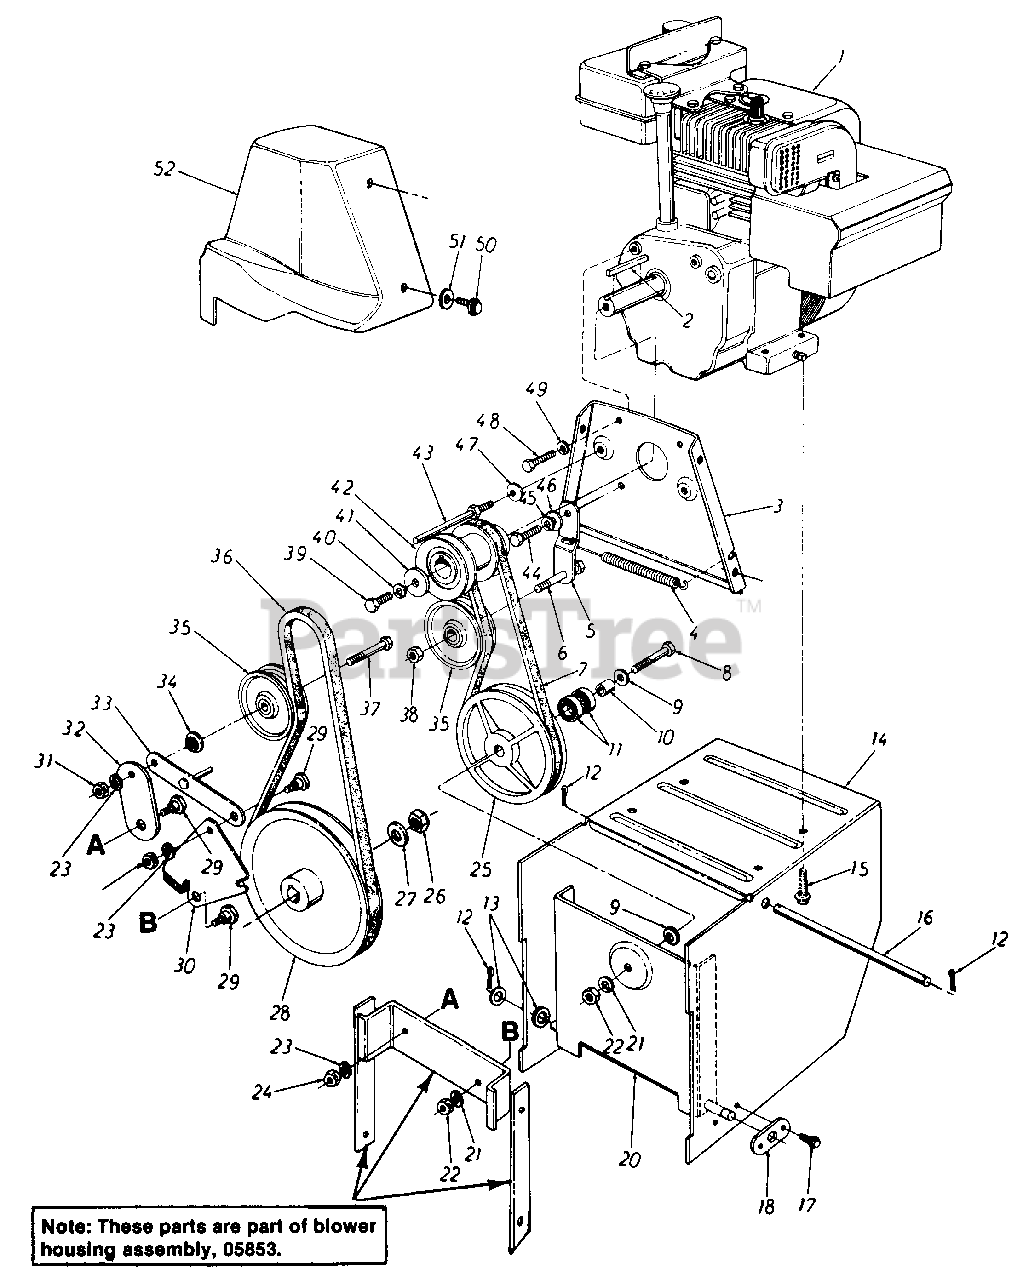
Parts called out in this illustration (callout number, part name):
1	Engine - 5 H.P.
2	Sq. Key 3/16" x 3/16" x 1.50" Lg.
3	Engine Plate Ass'y.
4	Extension Spring .38" O.D. x 3.25" Lg.
5	Drive Clutch Idler Brkt.
6	Hex Bolt 3/8-24 x 1.25" Lg.
7	"V"-Belt 3/8" x 29.0" Lg.
8	Hex Bolt 3/8-24 x 1.50" Lg.
9	Fl-Wash. .38" I.D. x .88" O.D. x .06
10	Spacer .38" I.D. x .62" O.D. x .75" Lg.
11	Ball Bearing
12	Cotter Pin 3/32" Dia. x .75" Lg.
13	Fl-Wash. .53" I.D. x 1.00" O.D. x .06
14	Frame Ass'y.
15	Hex Wash. Hd. Self-Tap Scr. 3/8-16 x 1.25" Lg.
16	Shaft .50" Dia. x 9.50" Lg.
17	Hex Wash. Hd. Self-Tap Scr 1/4-20 x .50" Lg.
18	Axle Bracket
20	Drive Pulley Support Brkt. Ass'y.
21	L-Wash. 3/8" I.D.
22	Hex Ins. Jam L-Nut 3/8-24 Thd.
23	L-Wash. 3/8" I.D.
24	Hex Ins. L-Nut 3/8-16 Thd.
25	6.00" O.D. Drive Pulley Ass'y.
26	Hex Jam Cent. L-Nut 5/8-18 Thd.
27	Fl-Wash. .64" I.D. x .94" O.D. x .06
28	1/2" V-Pulley .625" I.D. x 7.50" O.D.
29	Shld. Bolt .625" Dia. x .170" Lg. (3/8-16)
30	Brake Bracket Ass'y
31	Hex Ins. L-Nut 3/8-16 Thd.
32	Auger Clutch Idler Brkt.
33	Brake Linkage Ass'y.
34	Shld. Spacer .625" I.D.
35	Flat Idler 2.25" O.D.
36	"V"-Belt 3/8" x 38.0" Lg.
37	Hex Bolt 3/8-16 x 1.75" Lg.
38	Hex Ins. Jam L-Nut 3/8-24 Thd.
39	Hex Bolt 5/16-24 x 1.50" Lg.
40	L-Wash 5/16" I.D.
41	Fl-Wash .40" I.D. x 1.25" O.D. x .157
42	Double Groove Engine Pulley
43	Stud 3/8-16 x 3.62" Lg.
44	Hex Bolt 5/16-24 x 1.00" Lg.
45	L-Wash 5/16" I.D.
46	Shld. Spacer .320" I.D.
47	Bell-Wash. .40" I.D. x .88" x .06
48	Hex Bolt 5/16-24 x .62" Lg.
49	L-Wash 5/16" I.D.
50	Hex Wash. Hd. Self-Tap Scr. 1/4-20 x .50" Lg.
51	Fl-Wash. .28" I.D. x .75" O.D. x .06
52	Belt Cover
